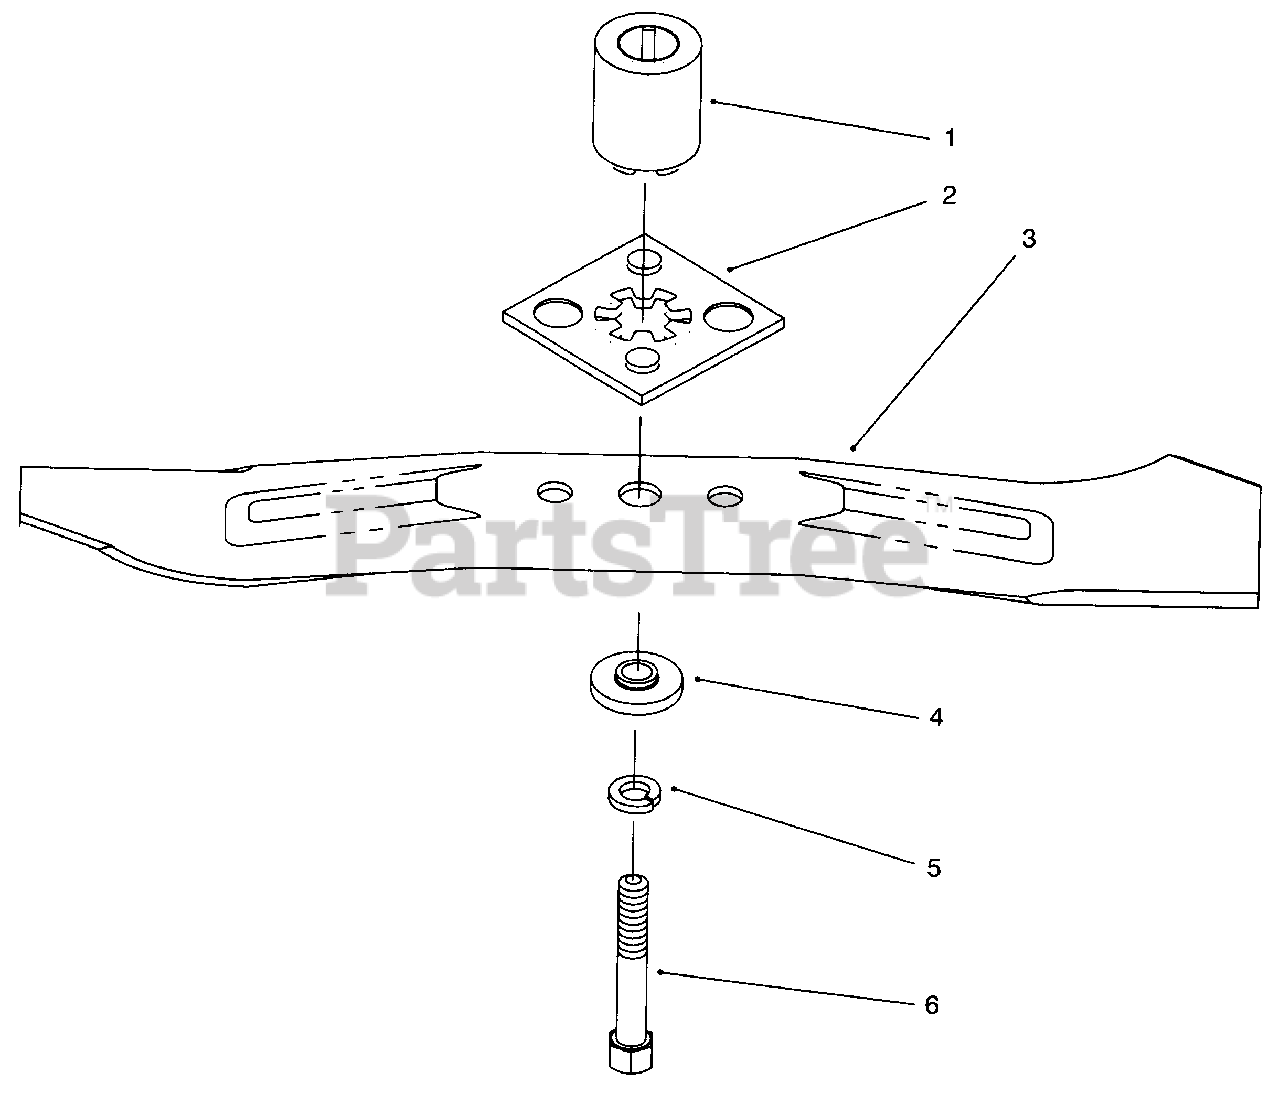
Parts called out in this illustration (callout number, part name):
1	Hub-Blade Driver
2	Plate-Blade Driver
3	Blade-48cm
4	Spacer-Blade
5	Washer-Lock
6	Bolt-Blade
